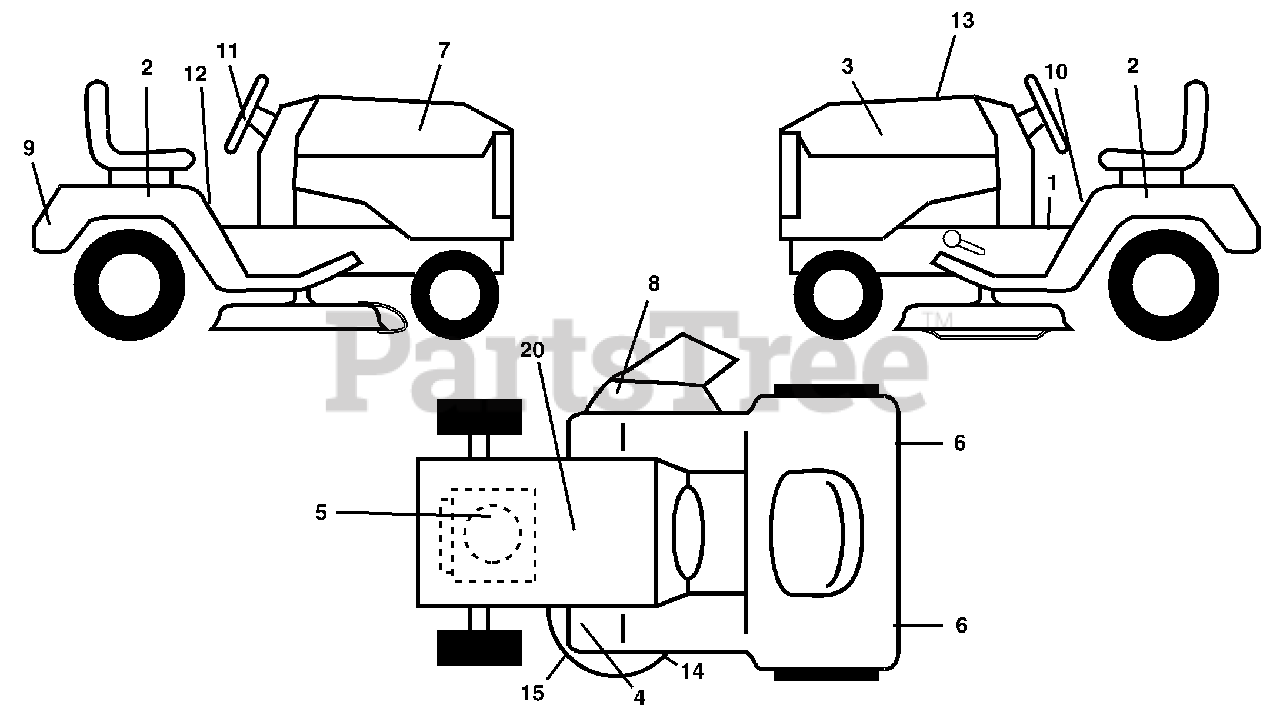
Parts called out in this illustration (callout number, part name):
1	Decal Dash
2	Decal Fender Auto
3	Decal Hood LH
4	Decal Footrest
5	Decal Tec 3yr Warranty
6	Reflector Tail Light
7	Decal Hood Rh
8	Decal Warning Mower
9	Decal Fender Logo
10	Decal Fender Danger E/F
11	Decal Ins Strg Whl
12	Decal Brake Parking
13	Decal Replace Part
14	Decal V-Belt Schematic
15	Decal Deck Caution
20	Decal Bat Dan/Psn
